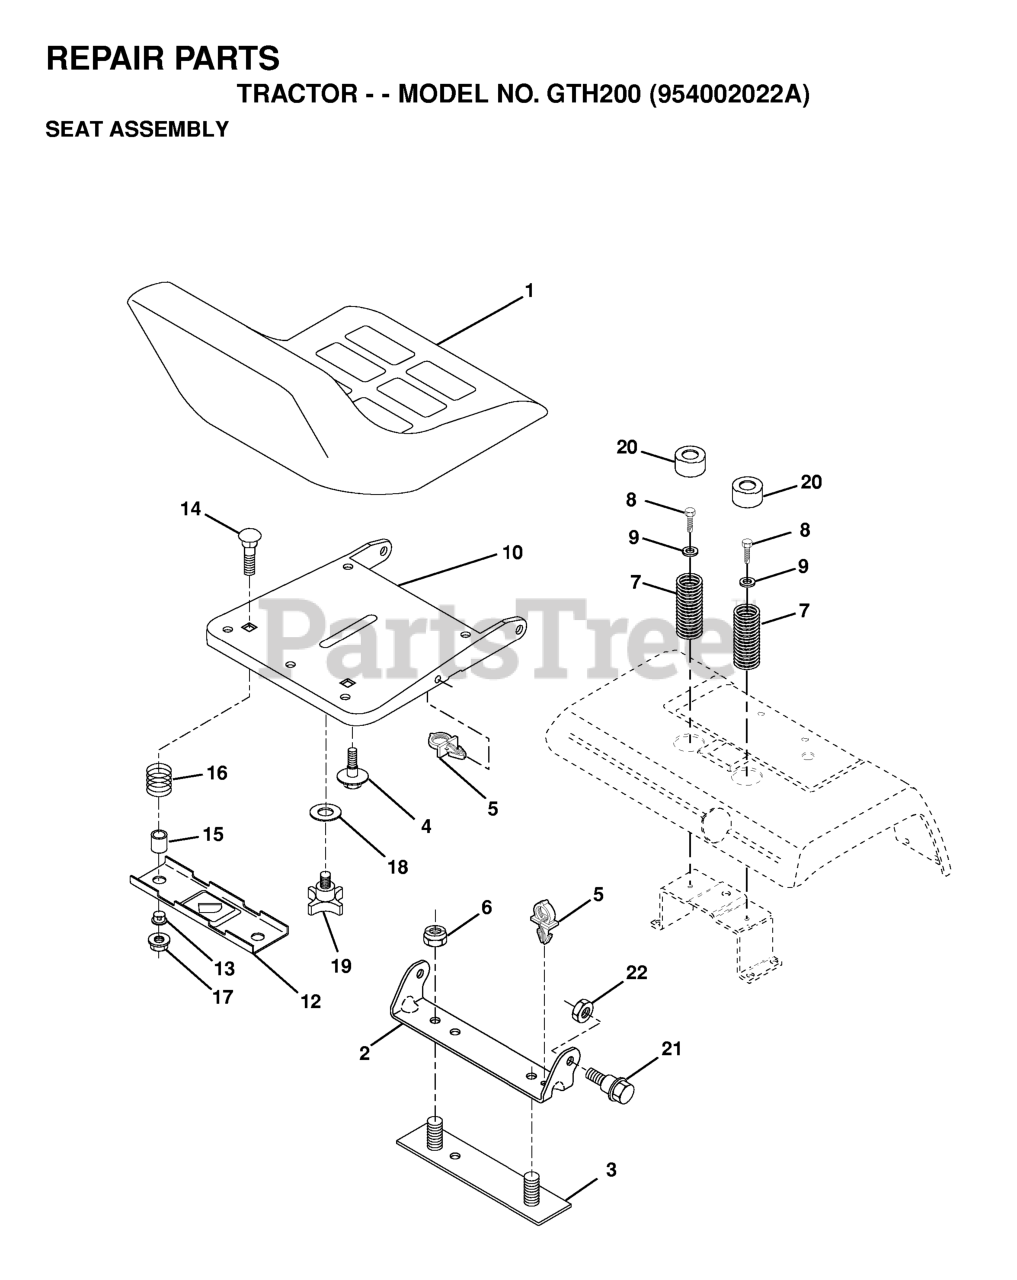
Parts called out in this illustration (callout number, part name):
1	SEAT
2	SEAT PIVOT BRKT
3	STRAP
4	BOLT,SHOULD
6	NUT
7	SPRING COMPRESSION
8	Screw 5/16-18 x 1/2 Hex, Self Tapping 5/16-18 x 1/2
9	WASHER
10	SEAT PAN
12	BRKT SWITCH
14	Bolt Rdhd. Sht. Nk 1/4-20 x 1-3/8
15	SPACER SPLIT
16	SPRING COMPRESSED
17	NUT T
19	KNOB 1/2" YT
20	CAP SPRING
21	BOLT.SHOULDER.5/16-18
22	LOCKNUT
